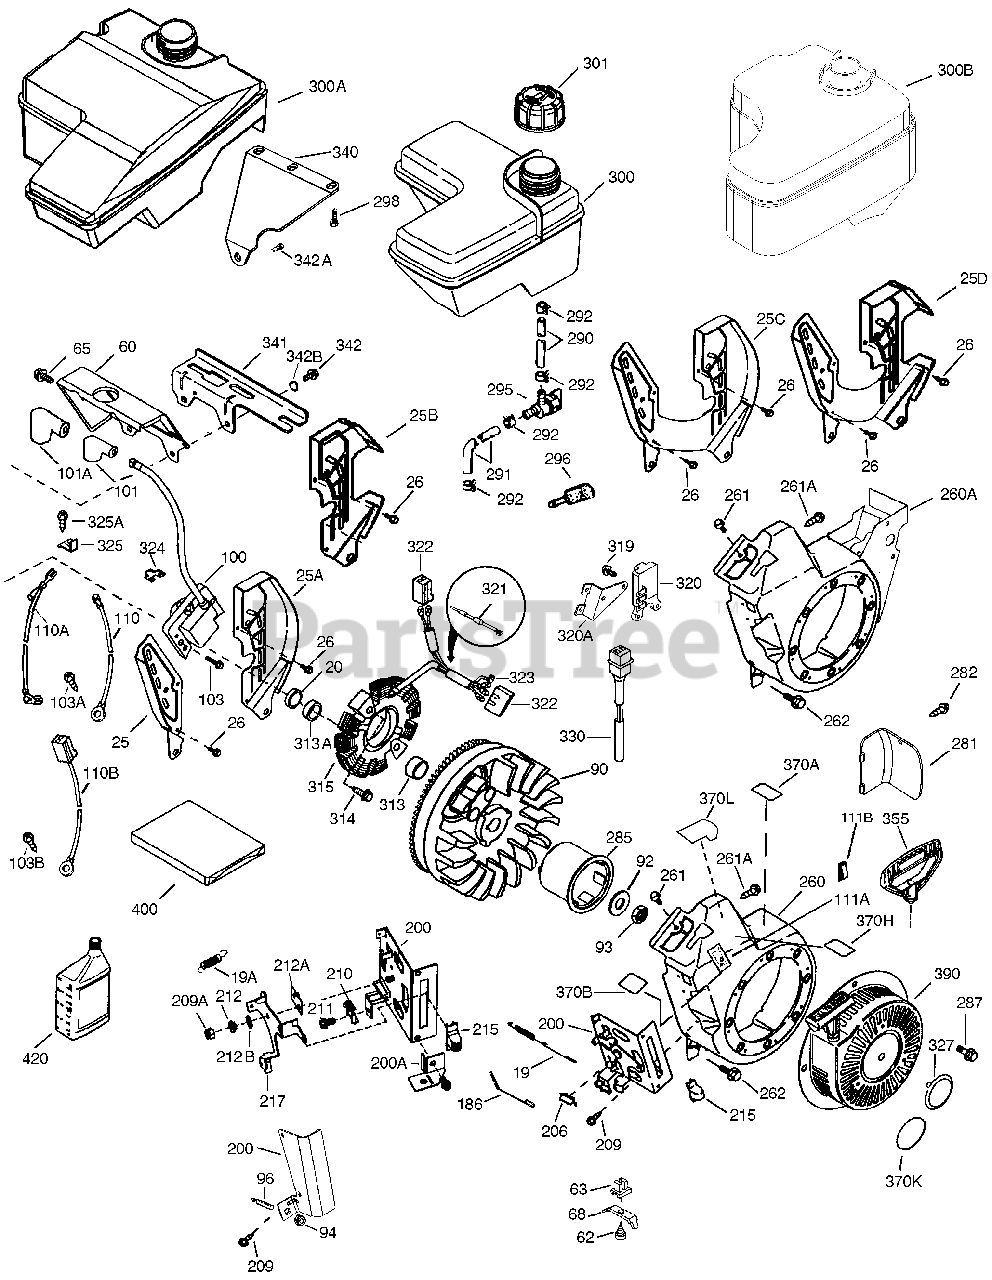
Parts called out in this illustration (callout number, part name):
19	Throttle Spring
20	Oil Seal
25C	Air Baffle (1 Piece)
60	Blower Housing Extension
62	Screw, 8-32 x 3/8"
65	Screw, 10-24 x 9/16"
90	Flywheel (Cast Iron)
92	Belleville Washer
93	Flywheel Nut
100	Solid State Ignition
101	Spark Plug Cover
103	Screw, T-15, 10-24 x 15/16"
110	Wire Harness (7" Y-form with ring ter minals) for use with 611226A switch
110A	Ground Wire
111B	Rocker On/Off Switch
173A	Breather Tube Grommet
186	Governor Link
200	Control Bracket (Incl. 206)
200A	Boden Wire Bracket
206	Terminal
210	Conduit Clip
211	Screw, 10-32 x 3/8"
215	Control Knob
229	Nut, 1/4-20
260	Blower Housing
285	Starter Cup
290	Fuel Line (16.0" length) Low Permeati on
292	Fuel Line Clamp
300B	Fuel Tank (Incl. 292 & 301) (3.5 Quar t)
301	Fuel Cap (Red Plastic)(1-1/2" I.D.)
338	Screw, 10-32 x 1/2"
341	Fuel Tank Bracket (Incl. 342 & 342B) Incl. 707 & 342B
342B	Washer (Rubber)
355	Starter Handle (Standard)
365	Screw, 8-32 X 27/64``
370	Speed Control Decal
370	Instruction Decal - Caution - read ow ner's manual
370	Decal - Tecumseh Logo for Top of Reco il Starter
370	Decal - Choke Lever - Off/Full
370	Decal - Low Oil Sentinel - Set of Lig ht & Switch Information
390	Rewind Starter Summer Pulley
400	Gasket Set (Incl. items marked *)
420	SAE 30 4-Cycle Engine Oil (Quart) (Su mmer)
701	Screw, 1/4-20 x 31/64"
707	Screw, 1/4-20 x 19/32"
999	Winter Maintenance Kit includes 32 oz . - SAE5W30 Oil, spark plug, switch k ey, fuel stabilizer
